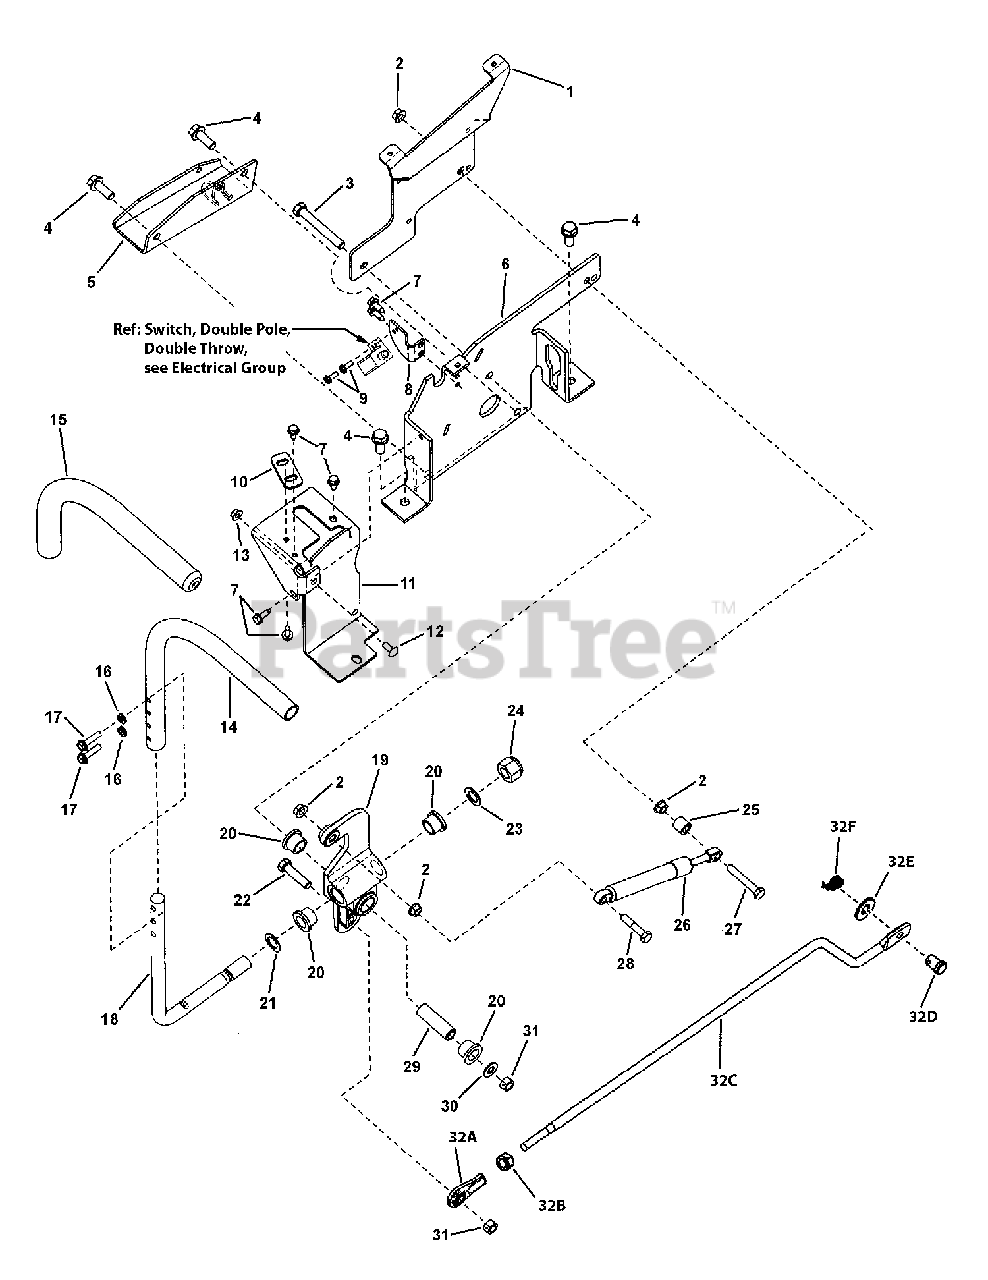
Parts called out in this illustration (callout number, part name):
1	BRACKET, Fender Support, RH
2	NUT, 5/16-18 Hex Flange Lock, GR 5, YZ
3	SCREW, 3/8-16 x 3-1/4" Hex Head Cap, GR 5
4	SCREW, 3/8-16 x 1" Hex Washer Self-Tap
5	BRACKET, Mount, Motor
6	CONTROL BRACKET, RH
7	SCREW, 1/4-20 x 3/4" Hex Washer Self-Tap, Black
8	BRACKET, Switch
9	SCREW, #10-24 x 1/2" Hex Washer Self-Tap, Torx
10	PLATE, Foward/Reverse Adjust
11	BRACKET, Guide, Stick, Control, RH
12	BOLT, 1/4-20 x 5/8" Round Head Short Square Neck, GR 5, YZ
13	NUT, 1/4-20 Hex Flange Lock, Black
14	HANDLE
15	GRIP, Handle
16	LOCKWASHER, 1/4" Spring, YZ
17	SCREW, 1/4-20 x 1" Hex Head Cap, GR 5, BZ
18	ROD, Handle, R.H.
19	ARM, Control Die Cast, RH
21	WASHER, .64 x .99 x .05 Flat, YZ
22	SCREW, 3/8-16 x 1-1/2 Hex Head Cap, GR 5, YZ
23	WASHER, 5/8 ID x 1.00 OD x .065 Nylon
24	NUT, 5/8-18 Hex Nyloc, YZ
25	SPACER
26	DAMPENER, Control
27	SCREW, 5/16-18 x 2" Hex Head Cap, GR 5, YZ
28	SCREW, 5/16-18 x 1-1/2 Hex Head Cap, YZ
29	SPACER, Sleeve, RZT
30	WASHER, 3/8" Flat (SAE)
31	NUT, 3/8-16 Hex Center Lock, YZ
32A	ROD END, (3/8-24 thread)
32B	NUT, 3/8-24 Hex, GR B, YZ
32C	ROD, Link Foward/Reverse (3/8-24 thread)
32D	PIN, 7/16 x 1" Clevis
32E	WASHER, 7/16" Flat
32F	COTTER PIN, 1/2 Self, YZ
